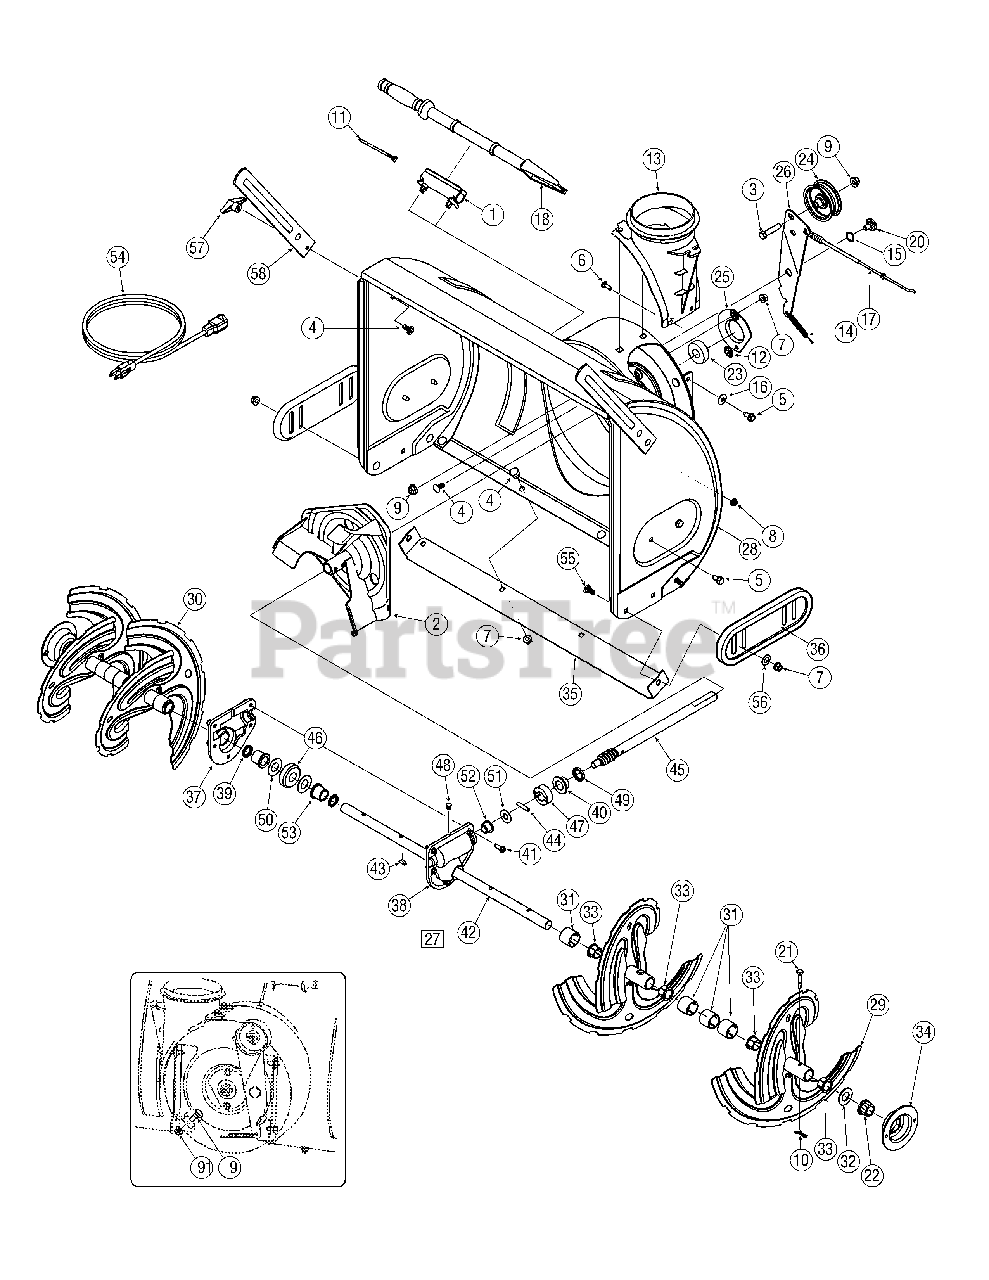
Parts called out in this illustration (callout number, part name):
1	Snow Removal Tool Mount
2	Impeller Assembly, 12" Dia.
3	Hex Screw, 3/8-16, 1.75, Gr5
4	Bolt, Carriage, 5/16-18, .750 Gr1
5	Screw, 5/16-18, 0.750
6	Screw, Carriage, 1/4-20, .750, Gr5
7	Nut, Flange Lock, 5/16-18, Nylon
8	Nut, Flange Lock, 1/4-20, Nylon
9	Nut, Flange Lock, 3/8-16, Nylon
10	Cotter Pin, Bow-tie
11	Cable, Tie, 3/16 x .05 x 7.4
12	Nut, Push-on, .25 Dia
13	Chute, Adapter 5" Dia
14	Spring, Extension, .38 OD x 4.59
15	Washer, Wave, .625 x .885 x .015
16	Washer, Bell, .340 x .872 x .060
17	Clutch Cable, Auger, 47.23"
18	Snow Removal Tool
19	Screw, Shoulder, .498 x .34, 3/8-16
20	Screw, Shoulder, .625 x .17, 3/8-16
21	Shear Pin, .25 x 1.50
22	Bearing, Hex Flange x .75 ID
23	Bearing, Ball, .75 ID x 1.85 OD
24	Flat Pulley, Idler, 2.75 OD
25	Housing, Bearing, 1.85 ID
26	Bracket, Auger Idler w/ Brake
27	Gearbox Assembly, Auger, 28"
28	Housing Assembly, Auger 28"
29	Spiral Assembly, LH
30	Spiral Assembly, RH
31	Spacer, 1.25 OD x .75 ID x 1.00
32	Washer, Flat, .76 x 1.49 x .06
33	Bushing, Flange, .80 ID x .91 OD
34	Housing, 1" Hex Bearing
35	Shave Plate, 2.25 x 27.66
36	Slide Shoe, Polymer Reversible
36	Polymer Reversible Shoe Kit
37	Housing, Auger, RH Reduced
38	Housing, Auger, LH Reduced
39	Seal, Oil, .750 x 1.00 x .125
40	Bearing, Flange, .75 x 1.0 x .59
41	Screw, Self-tapping, 1/4-20, 0.750
42	Axle, Auger, 28"
43	Key, Hi-pro 3/16 x 5/8
44	Pin, Dowel, .25 OD x 1.2
45	Shaft, Worm .75 OD
46	Gear, Worm 20T
47	Collar, Thrust
48	Plug, 1/4 x .437
49	Seal, Oil, .75 x 1 x .131
50	Washer, Flat, .760 ID x 1.5 OD
51	Washer, Flat, .51 x 1.12
52	Bearing, Flange, .75 x 1.0 x .925
53	Bearing, Flange, .75 x 1.00 x .975
54	Extension Cord, 110V
55	Screw, Carriage, 5/16-18 x 1.00
56	Washer, Flat, .349 x .879 x .063
57	Wing Knob
58	Drift Cutter
